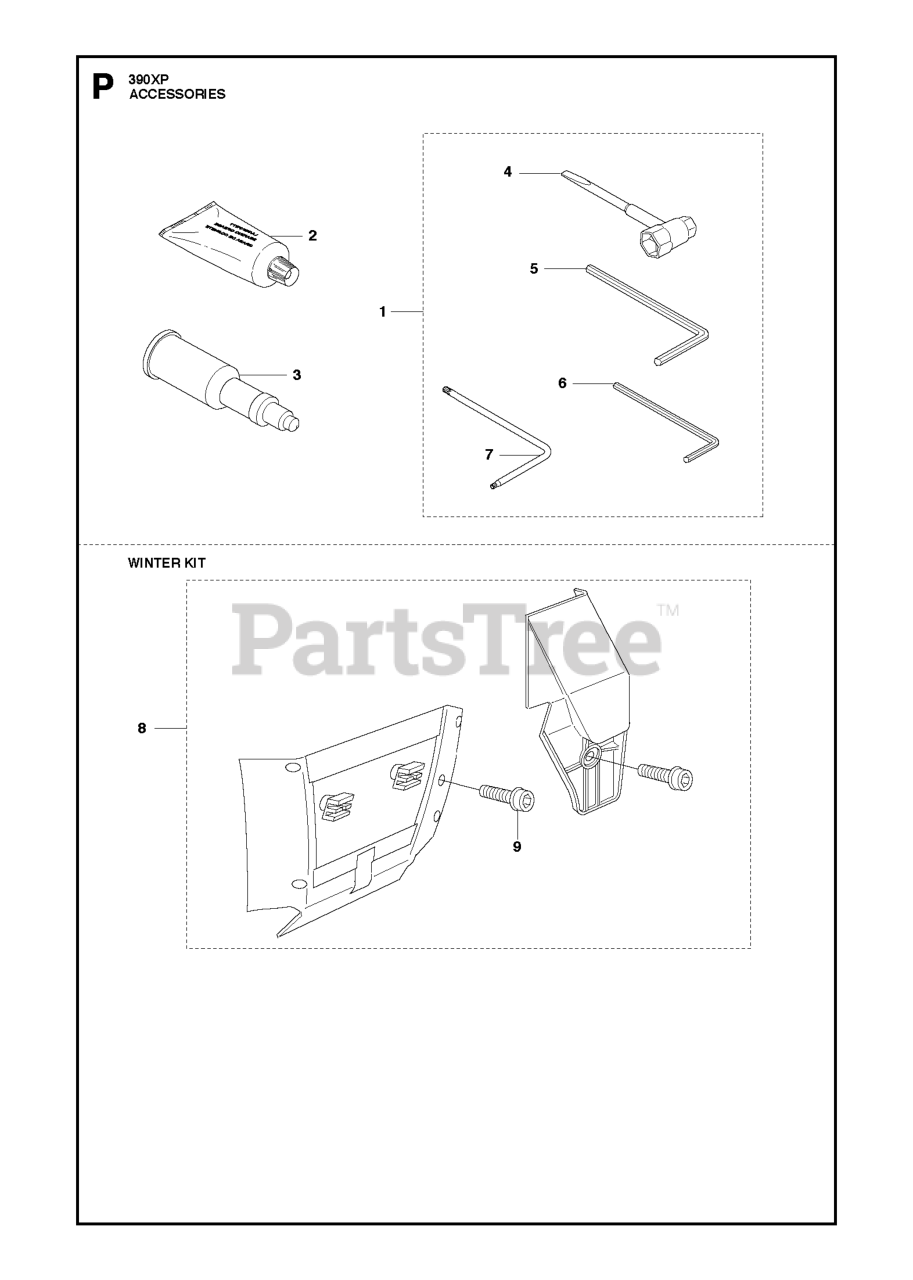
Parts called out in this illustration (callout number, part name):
2	GREASE
3	Grease Gun
4	COMBI TOOL
5	L-SPANNER
6	L-SPANNER
7	WRENCH
8	WINTER SET
